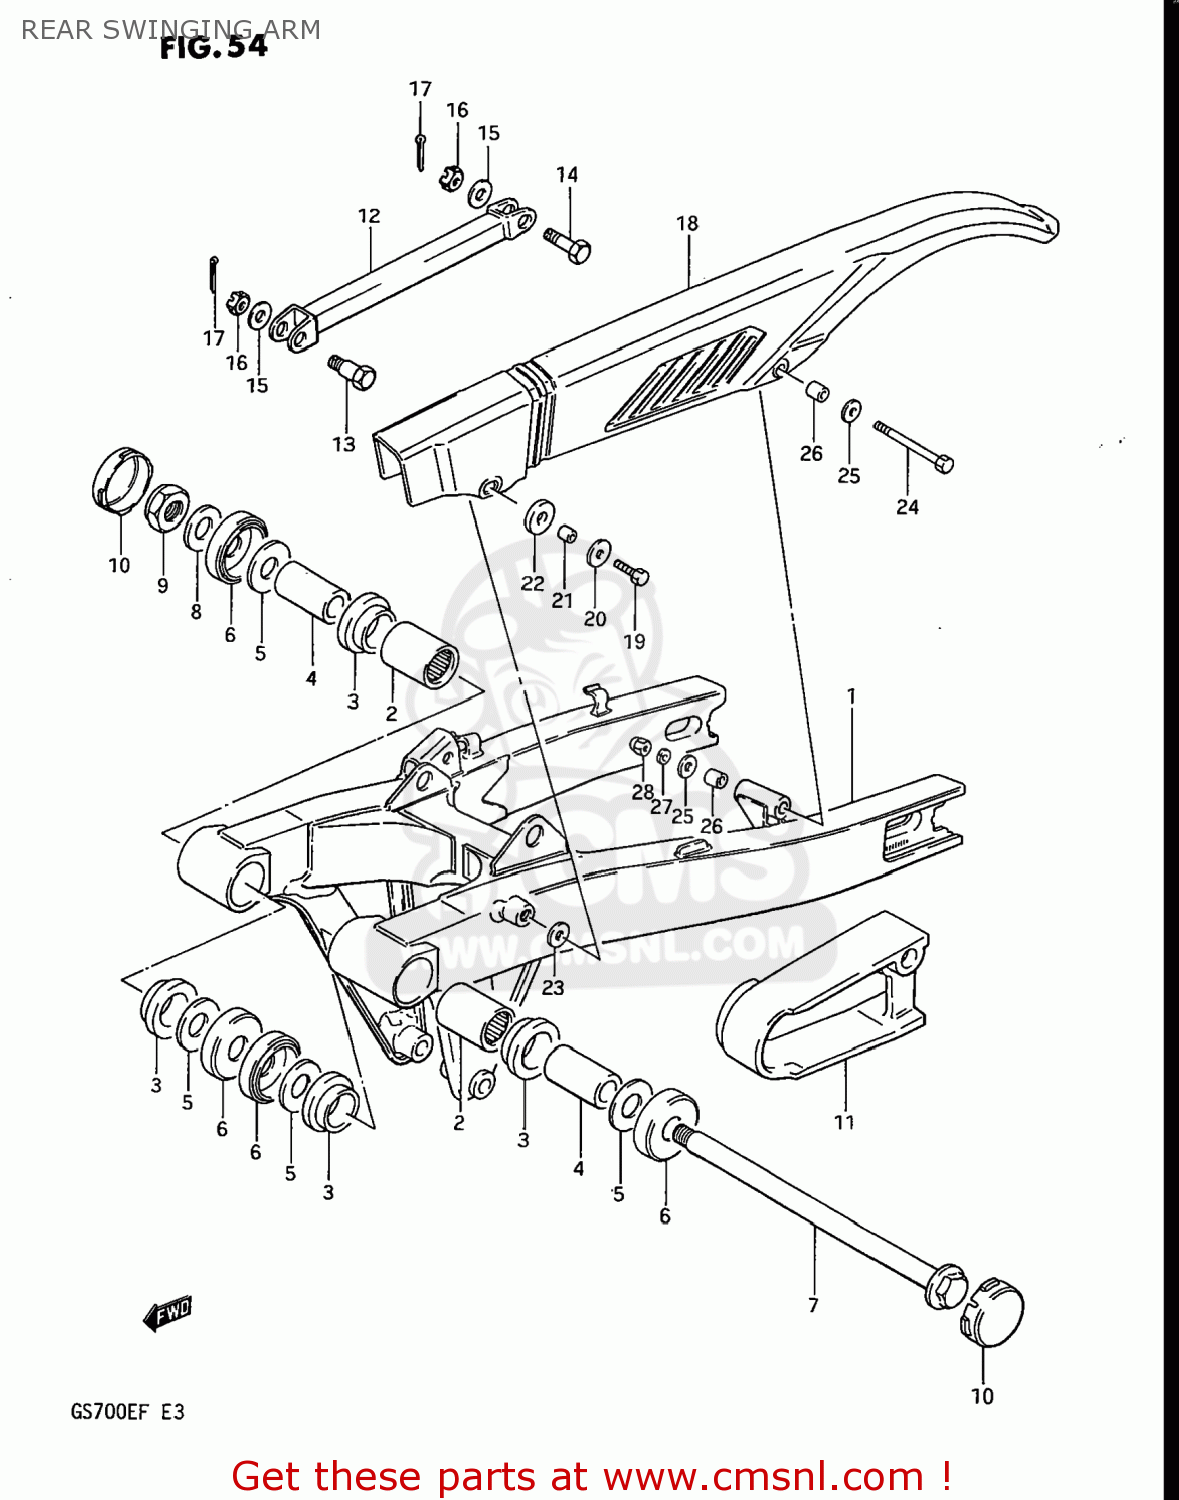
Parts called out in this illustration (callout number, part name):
1	SWING ARM ASSEMBLY,REAR
2	BEARING(25X33X30)
3	BUSHING
4	SPACER,RR SWGARM PIVOT
5	WASHER
6	COVER,RR SWINGINGARM PIVOT
7	SHAFT,REAR SWING ARM
8	WASHER
9	NUT
10	CAP,PIVOT
11	BUFFER,DEFENSE
12	TORQUE LINK,REAR
13	BOLT
14	BOLT(10X39)
15	WASHER
16	NUT
17	PIN 20X20
18	CASE,CHAIN
19	BOLT 6X16
20	WASHER (6.5X22X1.6)
21	SPACER
22	WASHER
23	WASHER (6.5X22X1.6)
24	BOLT 6X60
25	WASHER(6.5X18X1)
26	SPACER
27	WASHER,LOCK
28	NUT 6MM
